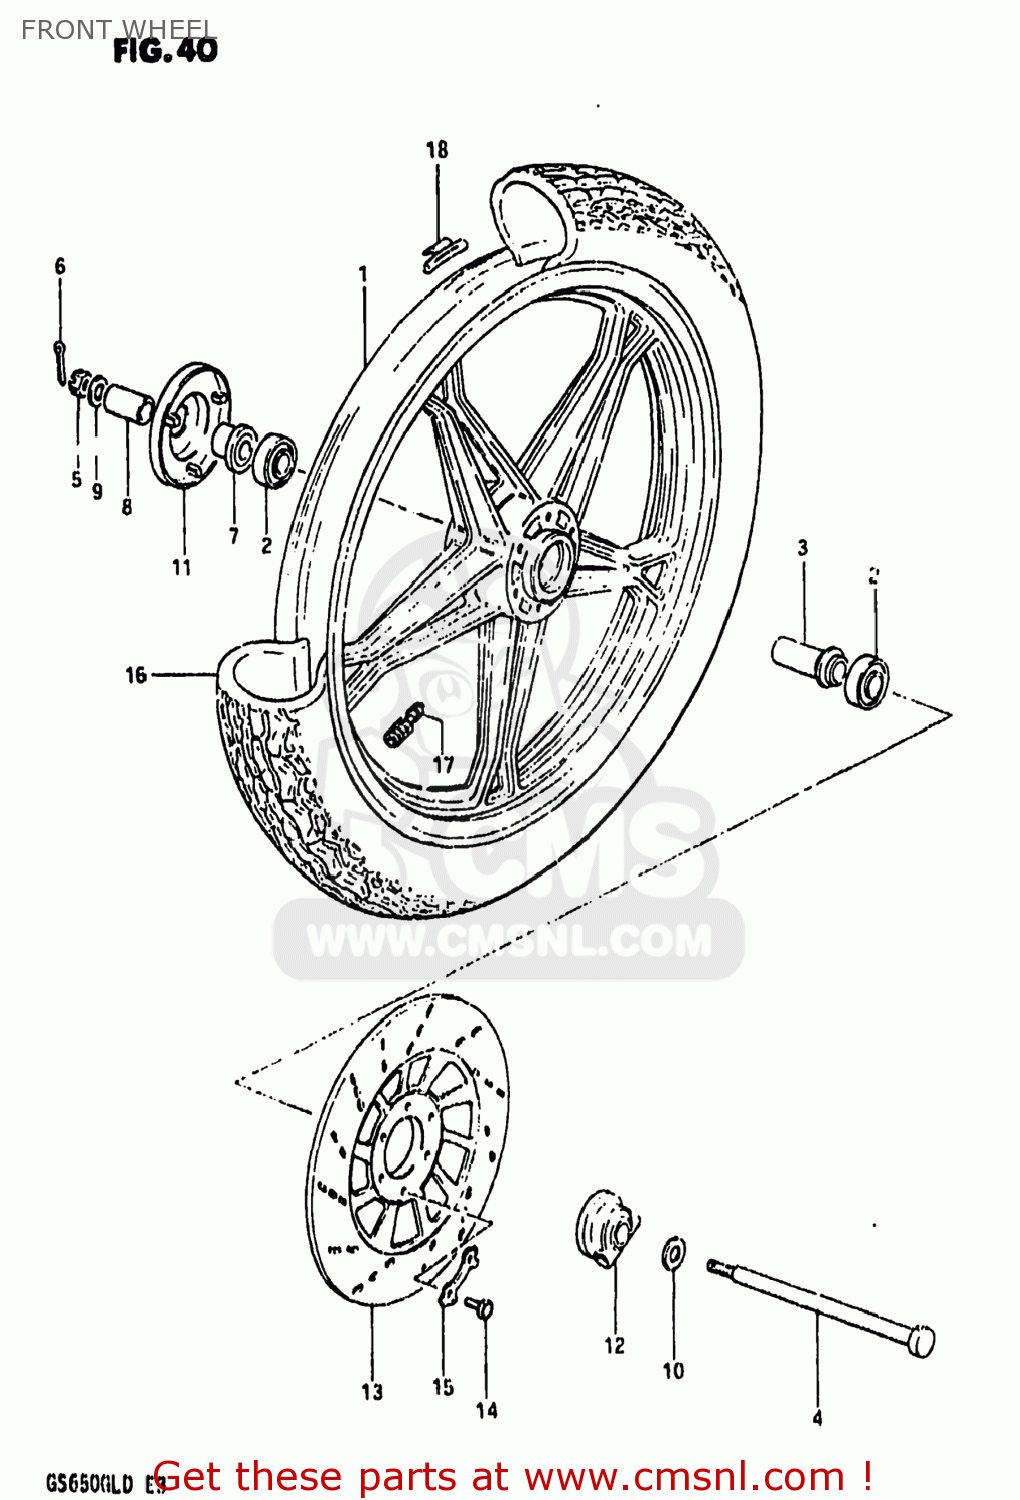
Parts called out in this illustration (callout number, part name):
1	CASTING WHEEL,FRONT 1.85
2	BEARING
3	SPACER,FR HUB BEARING
4	AXLE,FR
5	NUT 12MM
6	COTTER PIN
7	SPACER,FR AXLE,R
8	SPACER
9	WASHER
10	WASHER(15.5X26X2.3)
11	COVER,FR HUB,R
12	BOX ASSY,SPEEDOMETER GEAR
13	DISC,BRAKE
14	BOLT(8X25)
15	WASHER
16	TIRE,FRONT
17	VALVE ASSEMBLY,WHEEL RIM,J
18	BALANCER,WHEEL
